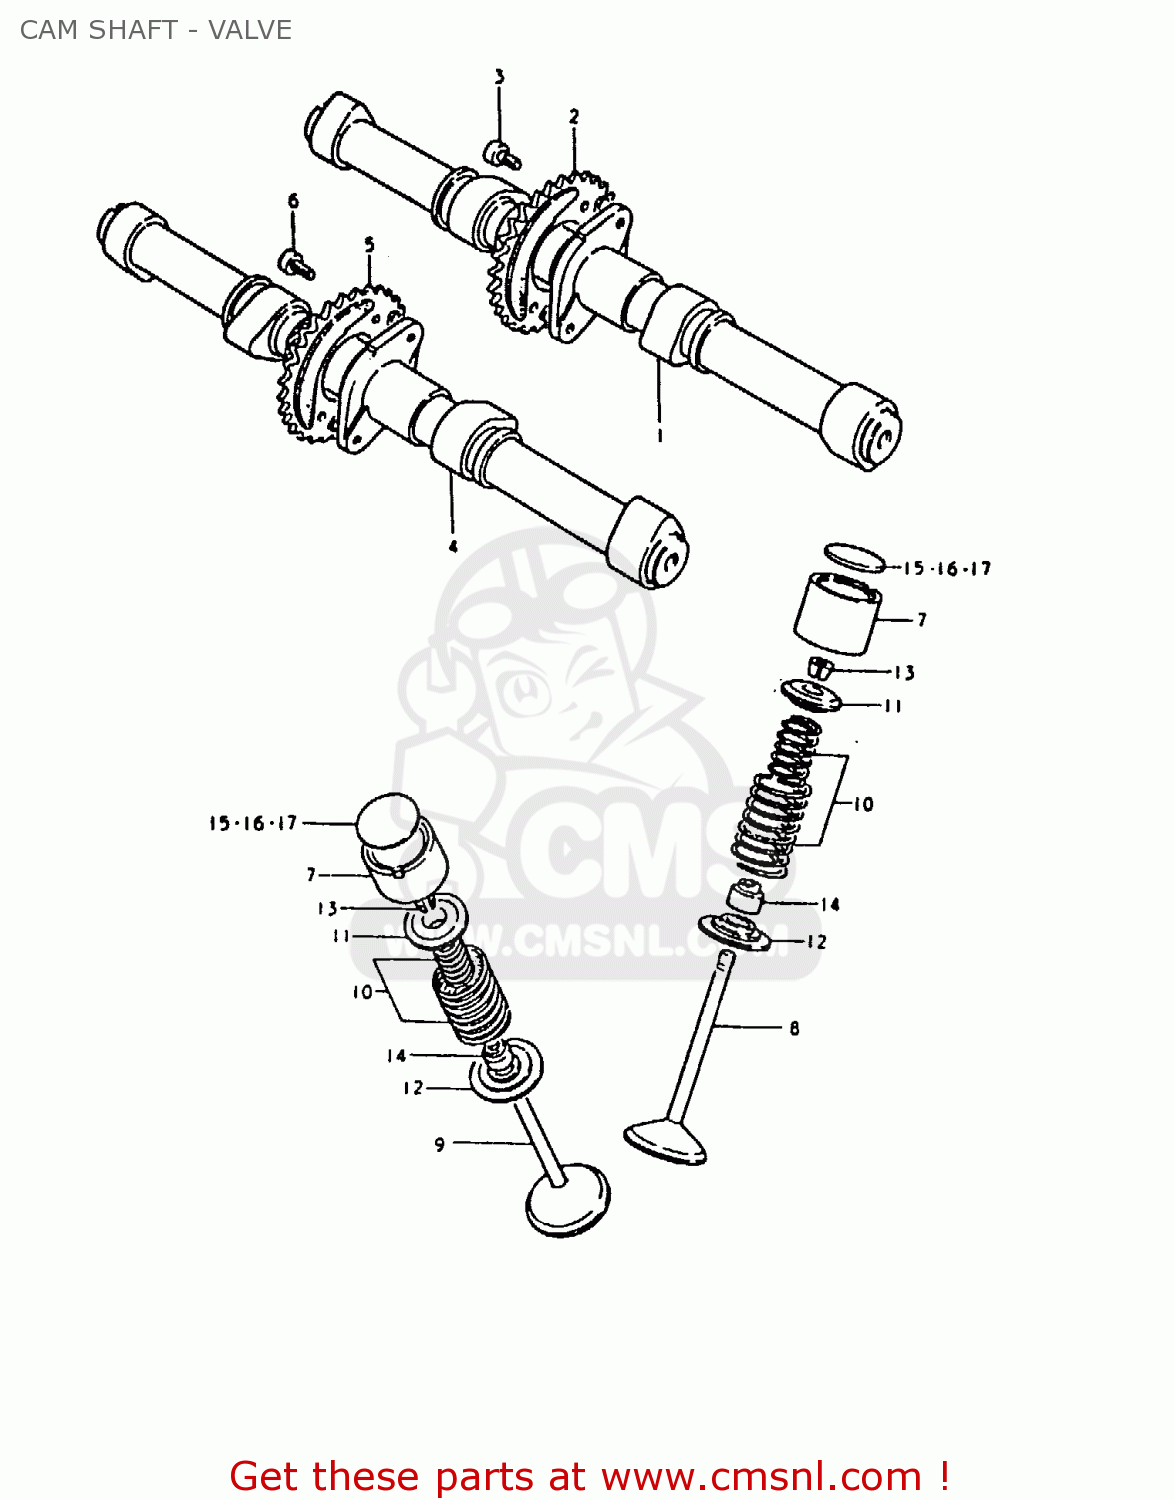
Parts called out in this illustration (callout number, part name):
1	CAMSHAFT
2	SPROCKET,INTAKE CAMSHAFT
3	BOLT 6X11
4	CAMSHAFT,EXHAUST
5	SPROCKET,EXHAUST CAMSHAFT
6	BOLT 6X11
7	TAPPET
8	VALVE,INTAKE
9	VALVE,EXHAUST
10	SPRING SET,VALVE
11	RETAINER,VALVE SPRING
12	SEAT,VALVE SPRING
13	COTTER VALVE
14	SEAL,OIL(7X14.4X9)
15	SHIM,TAPPET
16	SHIM,TAPPET
17	SHIM,TAPPET
